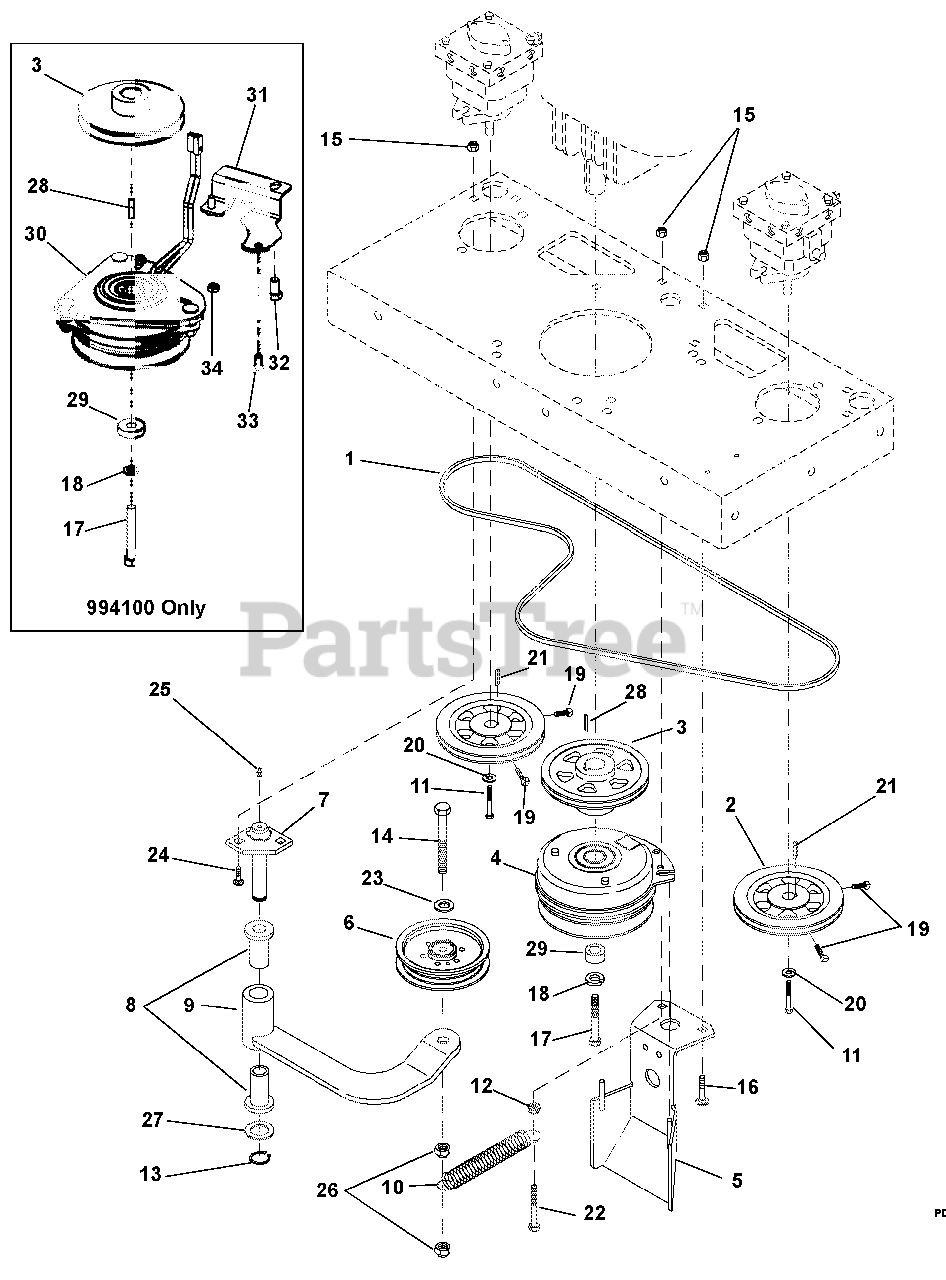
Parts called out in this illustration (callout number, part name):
1	V-Belt
2	Pulley, RH Pump, Set Screw Included
3	Pulley, Engine Drive
4	PTO Clutch (994103)
5	Bracket
6	Idler
7	Idler Post
8	Bushing
9	Idler Arm
10	Spring, Idler
11	Bolt, M6 x 1.00 x 10 Hex
12	Locknut, M10 x 1.50
13	Ring, Retaining, External .750 x .042
14	Bolt, Hex .38-16 x 2.50
15	Nut, Locking, Nylon M10-1.5
16	Carriage Bolt, M10 x 1.5 x 25
17	Bolt, Hex .44-20 x 3.00 Grade 5
18	Washer, Locking .44 x .109
19	Set Screw
20	Washer, Locking .250 x .077
21	Key, Special M5 x 28
22	Cap Screw, Spring Anchor, M10
23	Washer, Flat .406 x .812 x .065
24	Carriage Bolt, M10 x 1.5 x 25
25	Lubrication Fitting
26	Nut, Locking, Center .38-16
27	Bushing, 3/4 Machine
28	Key, .250 x .250 x .995 Taper
29	Spacer, PTO Clutch
30	Clutch Assembly, Ogura (994100)
31	Plate, Clutch Dog (994100)
32	Bolt, 7/16-14 x .750 Hex 5 (994100)
33	Bolt, Hex .31-18 x .75 Grade 5 (994100)
34	Nut, Locking, Nylon .312-18 (994100)
